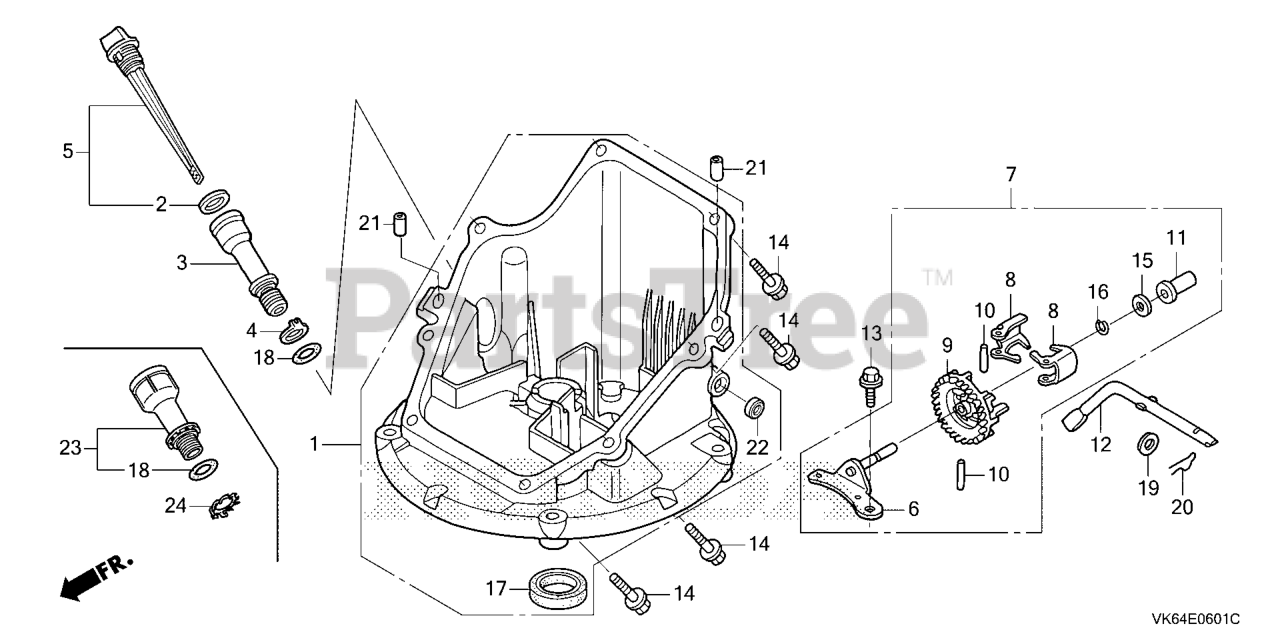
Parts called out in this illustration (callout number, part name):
1	PAN ASSY., OIL
2	GASKET, OIL FILLER CAP Use up to Engine SN 1257294.
3	EXTENSION, OIL FILLER
4	WASHER, EXTENSION LOCK
5	DIPSTICK, OIL
6	SHAFT, GOVERNOR HOLDER
7	GOVERNOR ASSY.
8	WEIGHT, GOVERNOR
9	HOLDER, GOVERNOR WEIGHT
10	PIN, GOVERNOR WEIGHT
11	SLIDER, GOVERNOR
12	SHAFT, GOVERNOR ARM
13	BOLT, FLANGE (6X14)
14	BOLT, FLANGE (6X25) Use up to Engine SN 2056819.
15	WASHER, THRUST (6MM)
16	CLIP, GOVERNOR HOLDER
17	OIL SEAL (28X41.25X6)
18	O-RING (14.8X2.4) (ARAI)
19	WASHER, PLAIN (6MM)
20	PIN, LOCK (8MM)
21	PIN, DOWEL (8X20)
22	OIL SEAL (6X11X4)
23	EXTENSION, OIL FILLER
24	WASHER, EXTENSION LOCK
